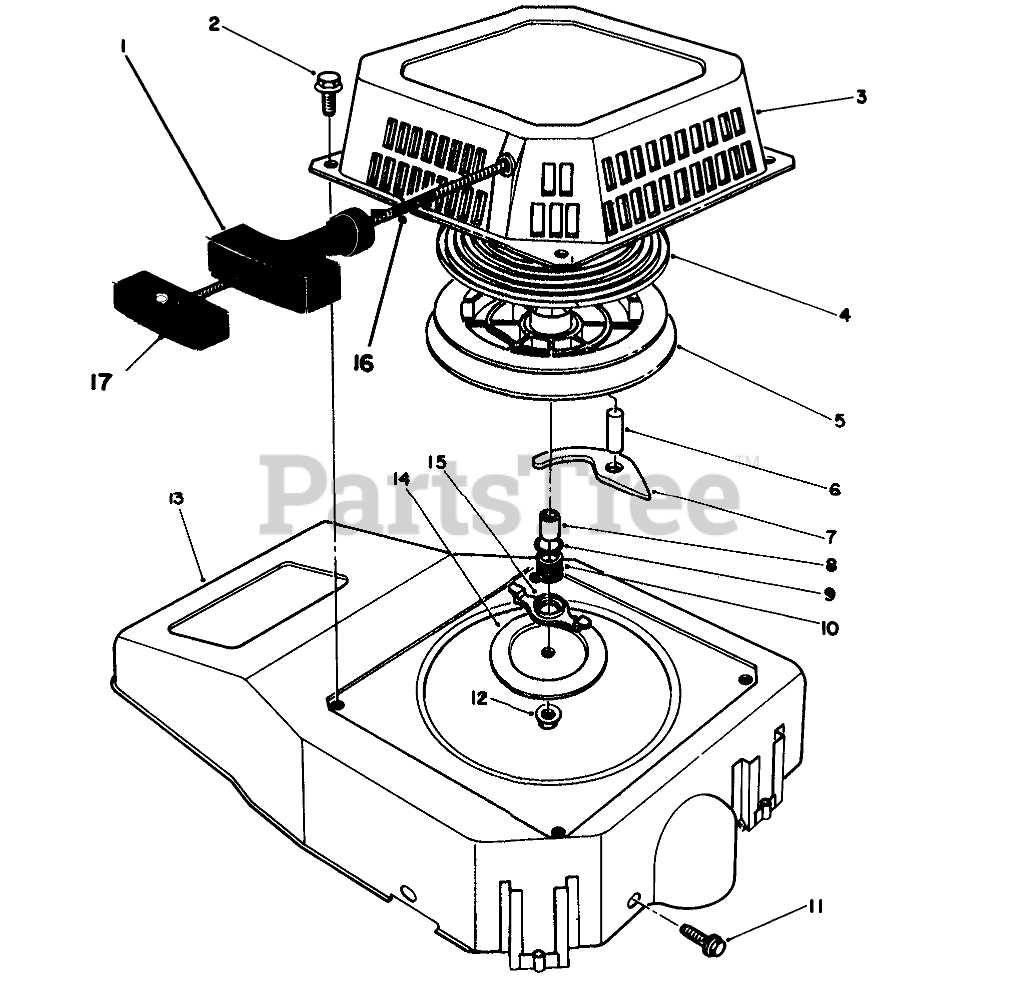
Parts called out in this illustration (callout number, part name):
1	HANDLE
2	SCREW-HHF
3	Case-Recoil
4	SPRING
8	Spacer
9	WASHER
10	Spring-Friction
13	SHROUD
14	PLATE
15	Guide-Paw
16	ROPE-STARTER
17	RETAINER HANDLE
